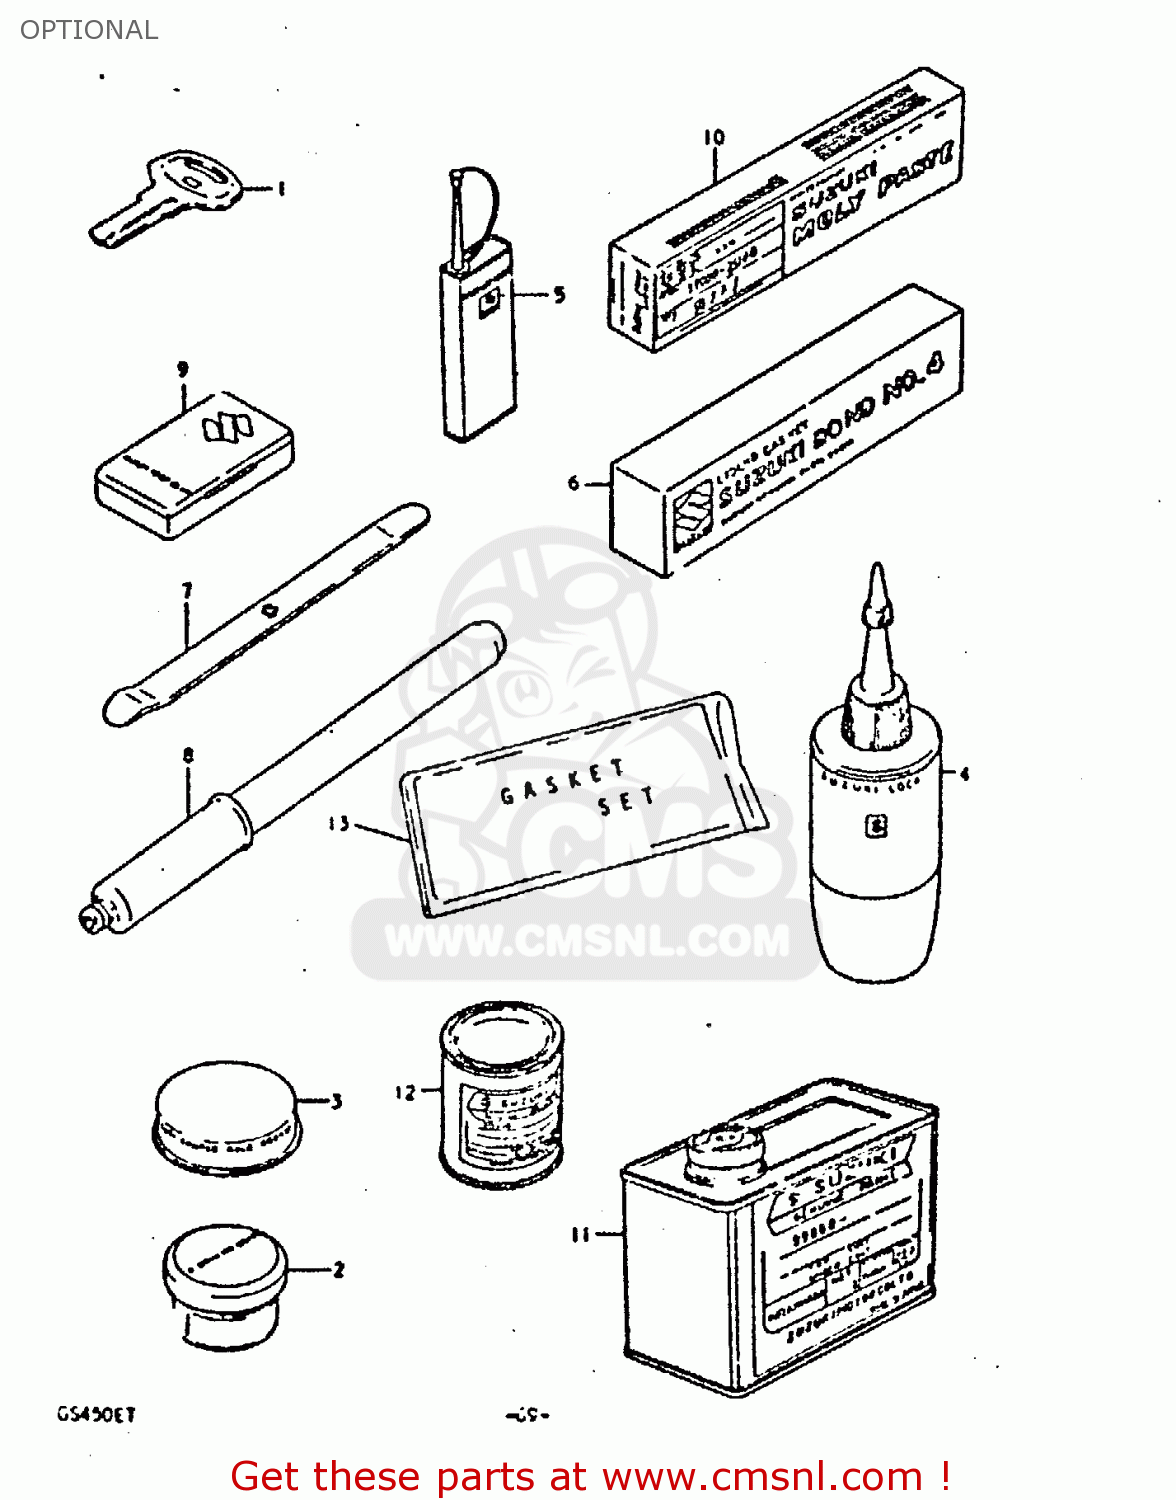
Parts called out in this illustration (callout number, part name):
1	KEY,BLANK
2	GREASE,PBC FOR BRK PAD 20G
3	GREASE,SILICON 20G
4	THREAD LOCK NO.1303B PURPL 50G
5	THREAD LOCK NO.1401 CLEAR 200G
6	BOND 1104
7	LEVER,TIRE
8	INFLATOR, AIR
9	TUBE REPARING TOOL
10	SUZUKI MOLY PASTE
11	PAINT (BLACK)
12	PAINT,BLACK
